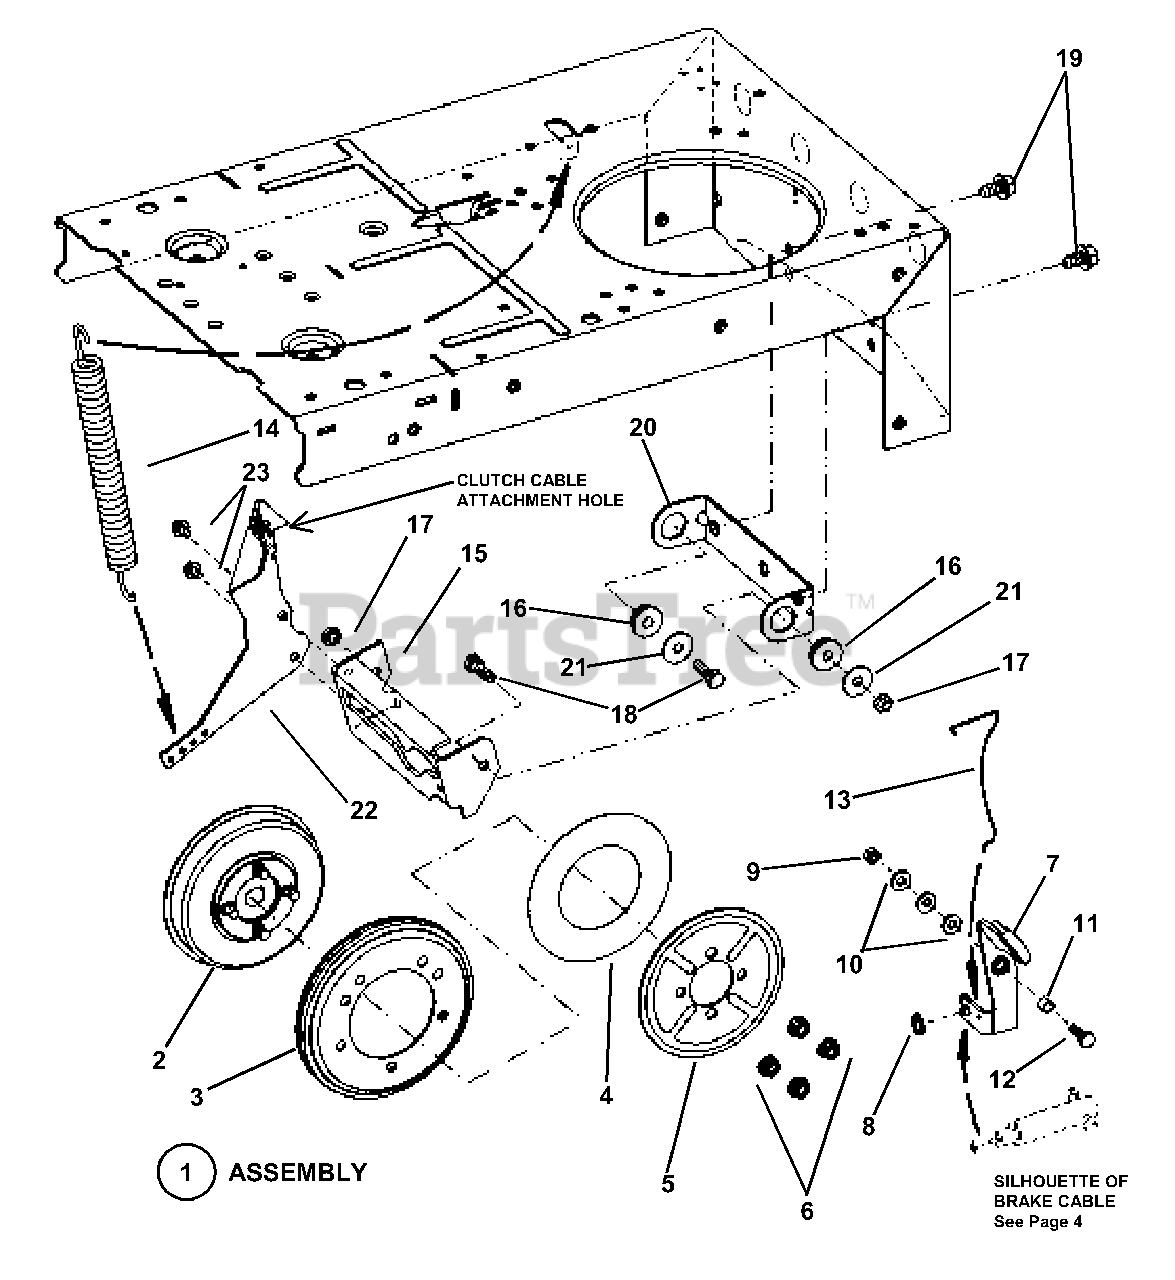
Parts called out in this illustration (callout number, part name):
1	ASSEMBLY, Smooth Clutch
2	ASSEMBLY, Driven Disc Hub
3	DISC, Driven
4	WASHER, Thrust
5	PLATE
6	NUT, 5/16-18 Hex Flange Lock
7	ASSEMBLY, Brake Lever
8	RING, 3/8" External Retaining
9	NUT, 1/4-28 Hex Top Lock
10	WASHER, 1/4 Flat
11	SPACER
12	SCREW, 1/4-28 x 1" Hex Head Cap, Grade 5
13	SPRING, Brake Return
14	SPRING, Clutch Brake
15	LIFT, Yoke
16	BEARING, Yoke
17	NUT, 5/16-24 Hex Center Lock
18	SCREW, 5/16-24 x 1" Hex Head Cap, Grade 5
19	SCREW, 3/8-16 x 5/8" Hex Washer Self-Tap
20	COLLAR, Yoke
21	WASHER, 5/16 Flat
22	ARM, Yoke
23	SCREW, 1/4-20 x 3/8" Hex Washer Self-Tap
